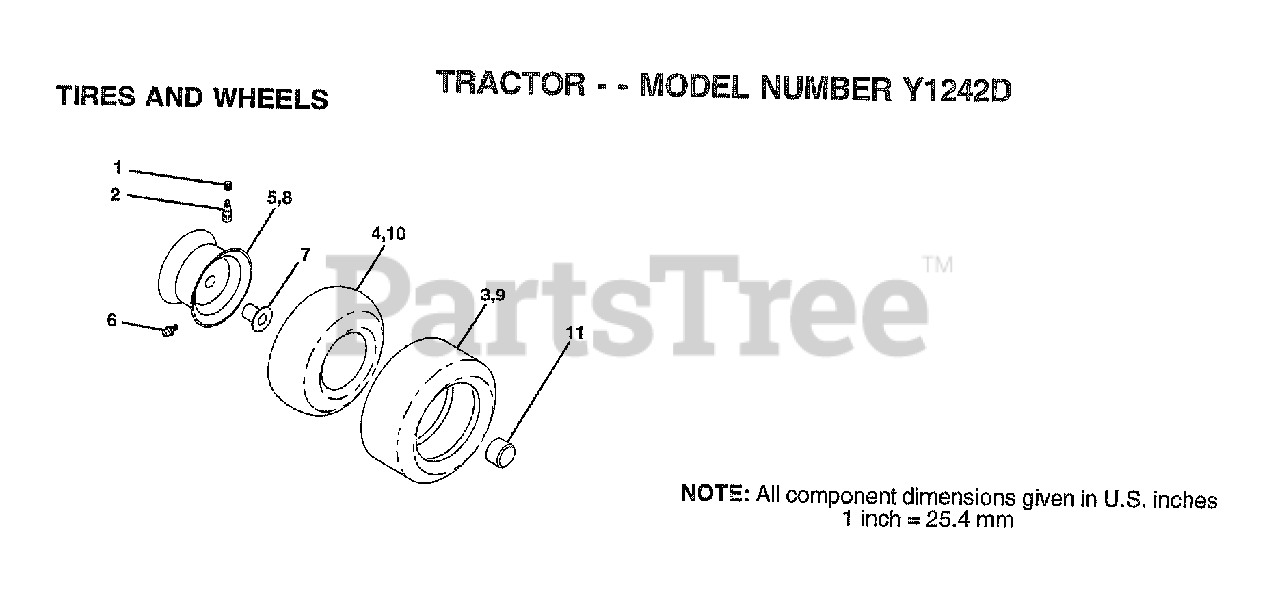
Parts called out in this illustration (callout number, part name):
1	VALVE CAP
2	VALVE STEM LT
4	TUBE.5.3/4.5/6
5	"RIM,FRT T"
6	FITTING LT
7	"FLANGE, BEARING"
8	"RIM 8"""
10	TUBE.18X9.5-8
11	HUB CAP
